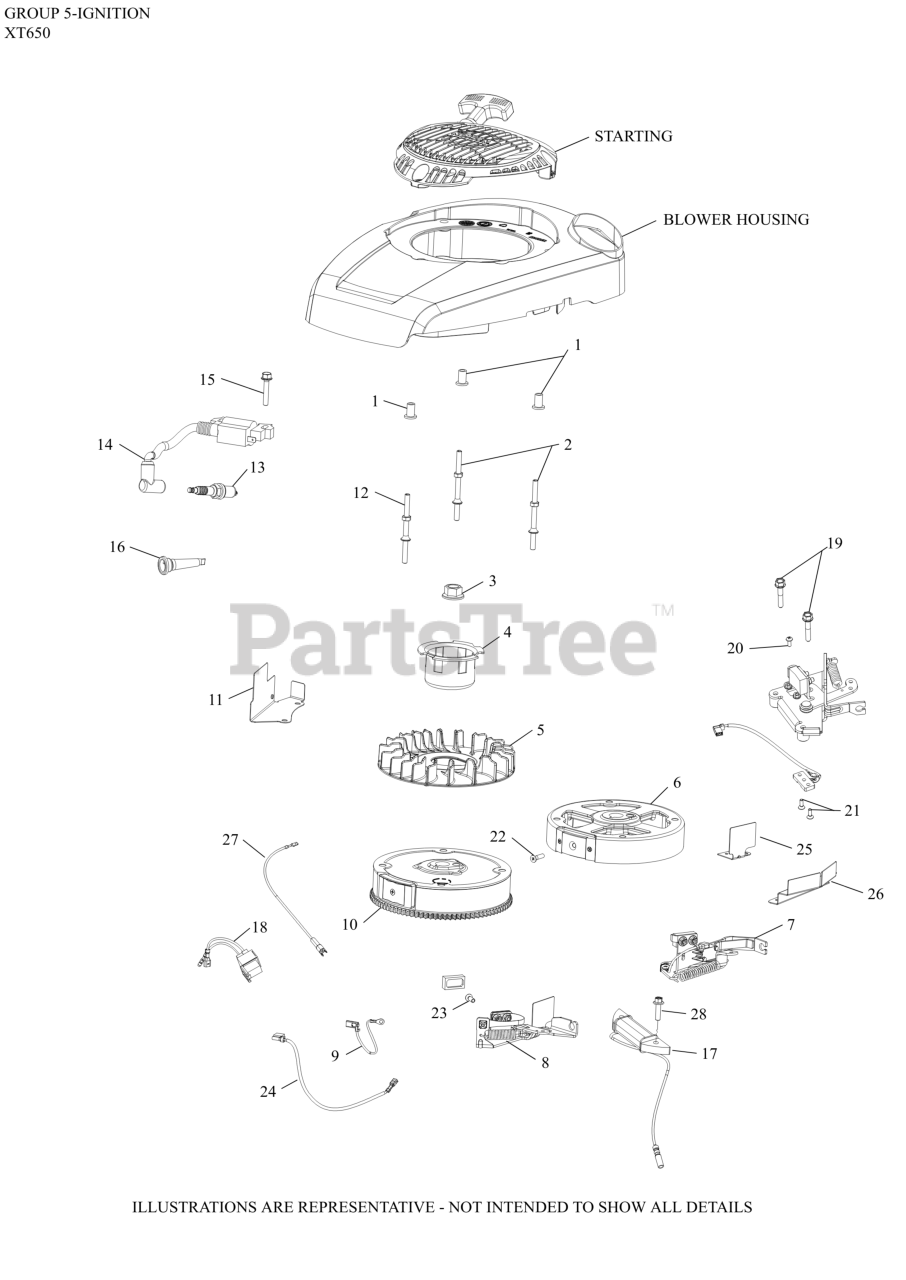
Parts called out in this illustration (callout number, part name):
2	STUD-USE 14 072 26-S
3	NUT, FLYWHEEL (W/SERRATIONS)
4	CUP, STARTER DRIVE
5	FAN, FLYWHEEL
6	FLYWHEEL ASSEMBLY-USE 14 025 12-S
8	BRAKE, ASSEMBLY-USE 14 219 17-S
9	LEAD, KILL-USE 14 518 28-S
9	LEAD, KILL (BRAKE TO IGN MODULE)
11	GUARD, FINGER
12	STUD-USE 14 072 25-S
13	PLUG SPARK 12MM RFI
14	MODULE IGN (#1458416S)
15	SCREW, M6 X 25-(#25086436S)
25	GUARD, BRAKE - USE 14 314 30-S
